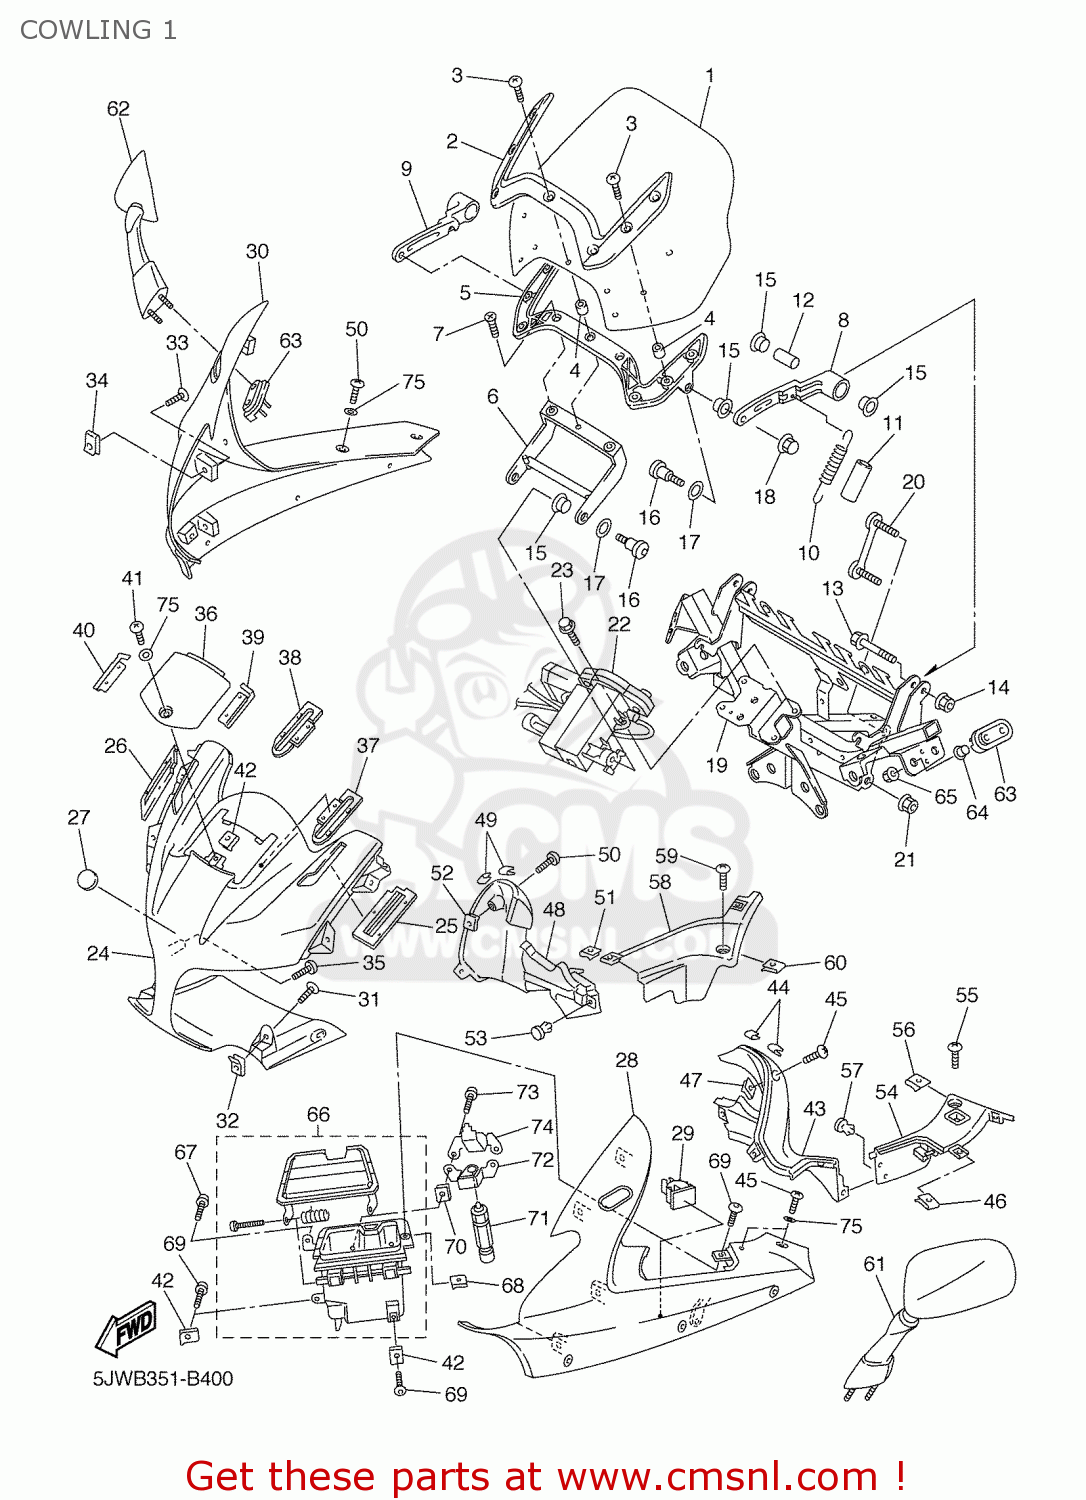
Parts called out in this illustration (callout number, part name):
01	WINDSHIELD
02	WASHER, LEG SHIELD
03	SCREW, COWLING 1
04	NUT(1KT)
05	STAY 2
06	STAY, LEG SHIELD
07	SCREW (1FK)
08	LINK 1
09	LINK 2
10	SPRING, TENSION(4GB)
11	HOSE (L35)
12	COLLAR (8F2)
13	BOLT, FLANGE
14	NUT, SELF-LOCKING(JN5)
15	SPACER
16	BOLT, COWLING
17	WASHER, PLATE (655)
18	NUT, CROWN
19	STAY 1
20	PLATE
21	NUT, FLANGE(8AB)
22	DRIVE UNIT ASSY
23	BOLT, FLANGE(4DU)
24	BODY, COWLING
25	SEAL 1
26	SEAL 2
27	TUNING FORK MARK
28	BODY, FRONT UPPER 1
29	CLAMP
30	BODY, FRONT UPPER 2
31	BOLT, HEXAGON SOCKET HEAD(3GM)
32	NUT, SPRING (26H)
33	BOLT, HEXAGON SOCKET HEAD(3GM)
34	NUT, SPRING (26H)
35	SCREW, TAPPING(4MV)
36	COVER
37	SEAL 3
38	SEAL 4
39	SEAL 5
40	SEAL 6
41	BOLT
42	NUT, SPRING(3GM)
43	PANEL, CONSOLE 1
44	SEAL
45	BOLT
46	NUT, SPRING (26H)
47	NUT, SPRING(3GM)
48	PANEL, CONSOLE 2
49	SEAL
50	BOLT
51	NUT, SPRING (26H)
52	NUT, SPRING(3GM)
53	RIVET
54	PANEL, INNER 3
55	BOLT
56	NUT, SPRING (26H)
57	RIVET(4JH)
58	PANEL, INNER 4
59	BOLT
60	NUT, SPRING (26H)
61	REAR VIEW MIRROR ASSY(LEFT)
62	REAR VIEW MIRROR ASSY(RIGHT)
63	PLATE, MIRROR FITTING 1
64	C0LLAR (3JB1)
65	NUT, FLANGE(4MV)
66	BOX SUB ASSY
67	SCREW, TAPPING
68	NUT, SPRING(3GM)
69	BOLT, HEXAGON SOCKET HEAD(3GM)
70	NUT, SPRING (26H)
71	LOCK ASSY
72	BRACKET
73	BOLT, HEXAGON SOCKET HEAD(3GM)
74	BRACKET
75	WASHER, PLATE(1KT)
